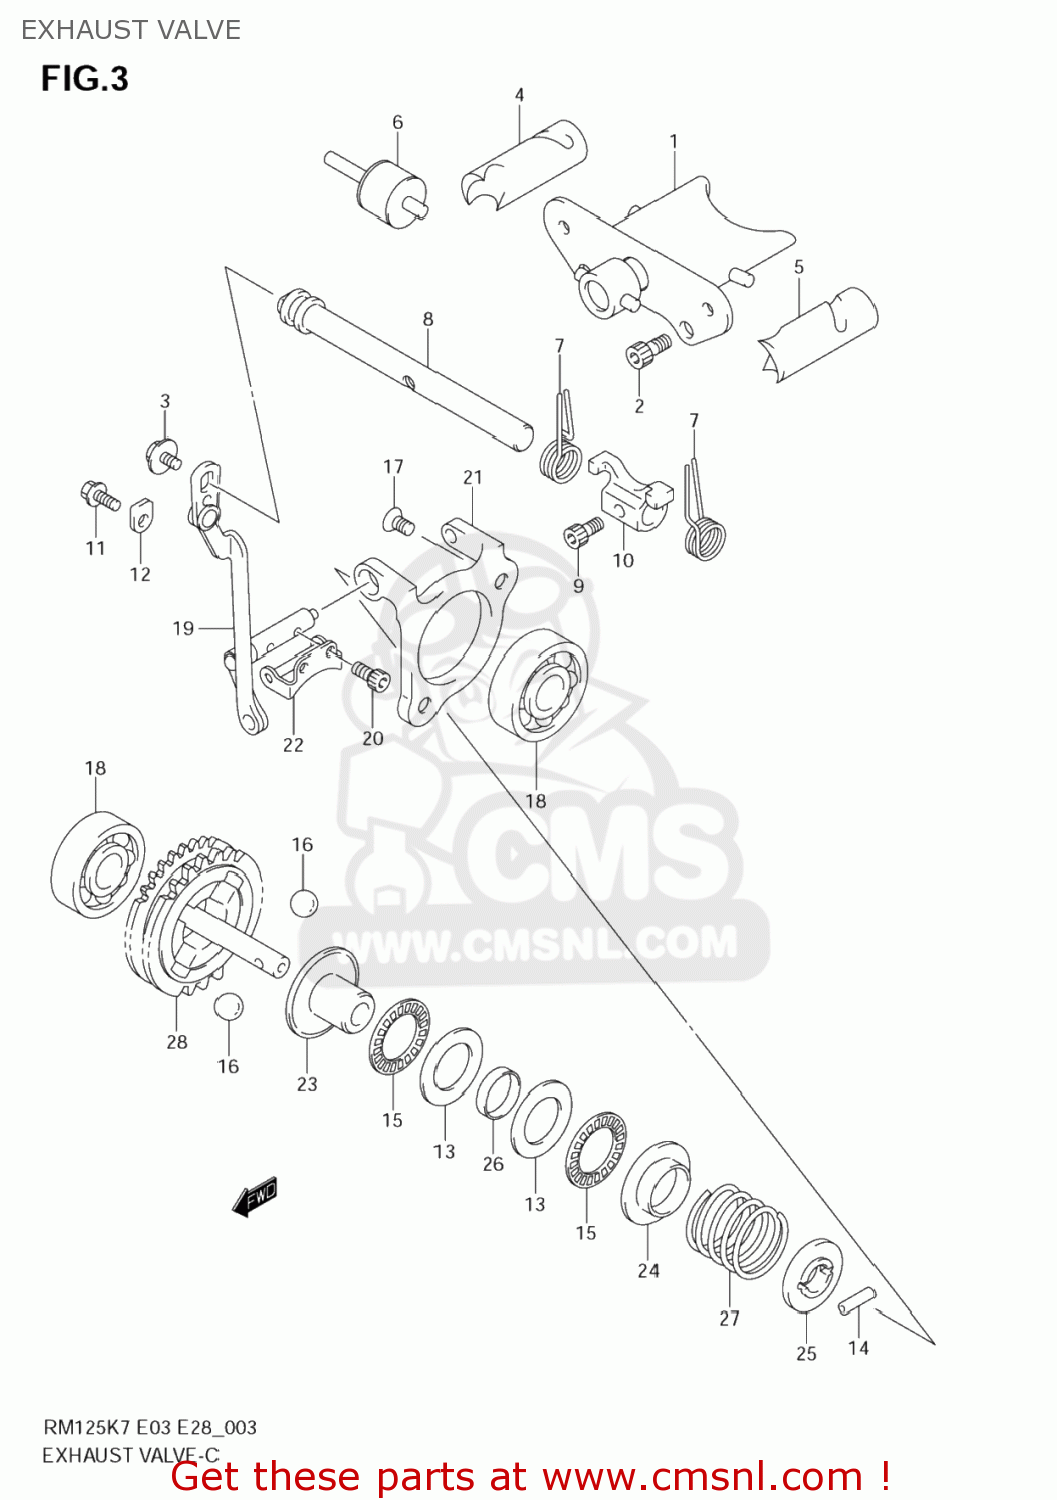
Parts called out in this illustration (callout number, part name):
1	VALVE ASSY,EXHAUST MAIN
2	BOLT
3	BOLT(5X10)
4	VALVE,EXHAUST SIDE,R
5	VALVE,EXHAUST SIDE,L
6	SHAFT,EXHAUST SIDE VALVE
7	SPRING,EXHAUST VALVE SHAFT ARM
8	SHAFT,EXHAUST VALVE
9	BOLT(4X8)
10	ARM,EXHAUST VALVE SHAFT
11	BOLT(6X10)
12	RETAINER
13	SHIM(15X28X1)
14	ROLLER(3X12.5)
15	BEARING(15X28X2)
16	BALL
17	SCREW(5X10)
18	BEARING(8X22X7)
19	ACTUATOR,EXHAUST VALVE
20	BOLT(4X8)
21	BASE,ACTUATOR
22	ARM,ACTUATOR
23	GOVERNOR,DRIVEN
24	STOPPER,GOVERNOR SPRING NO.1
25	STOPPER,GOVERNOR SPRING NO.2
26	SPACER,GOVERNOR
27	SPRING,GOVERNOR
28	GOVERNOR SET,EXHAUST
